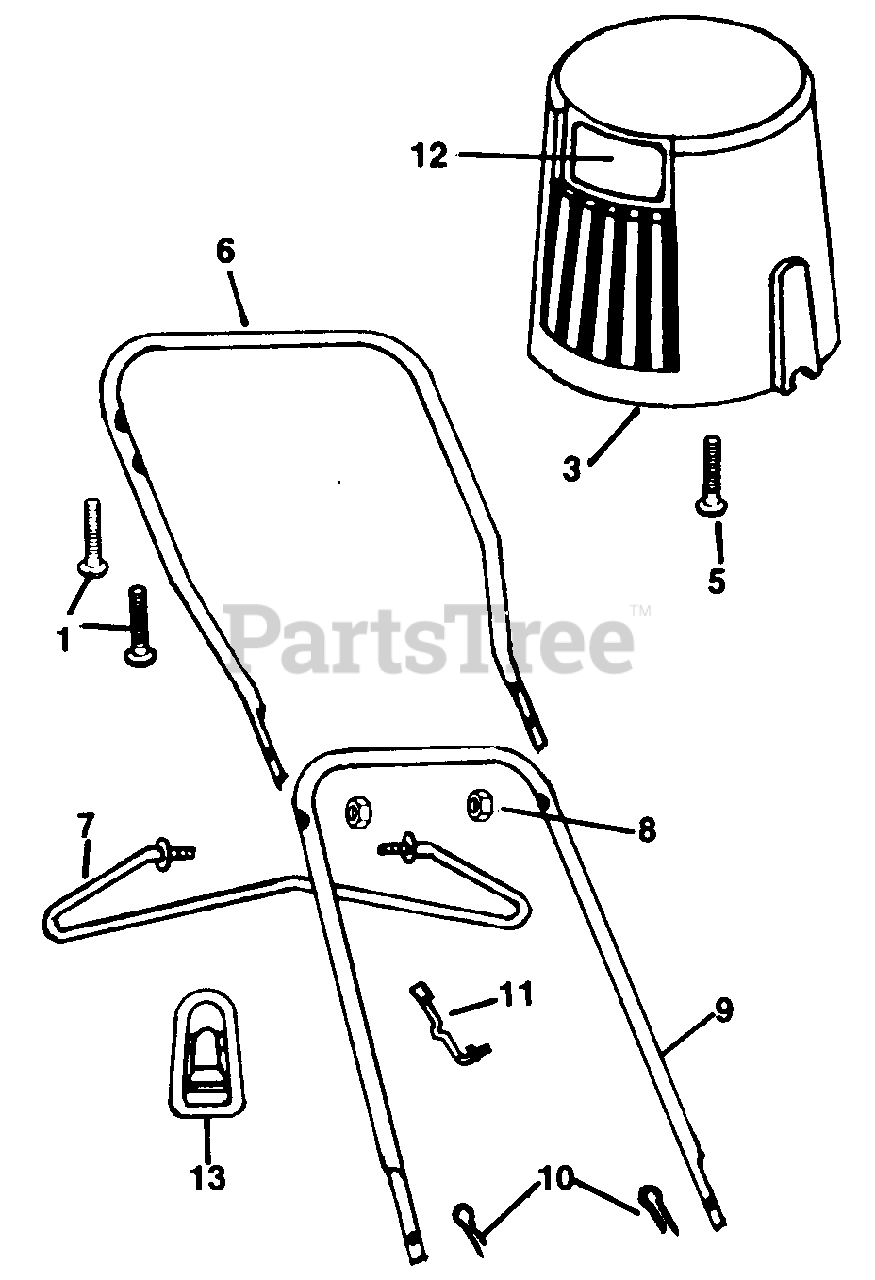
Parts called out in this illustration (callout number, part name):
1	Screw
3	Plastic Shroud
5	10-16 x 3/4" T25 Tapping
6	Upper Handle
7	Cord Control Rod
8	1/4"-20 Locknut
9	Lower Handle
10	CoKer Pin 3/32" x 1/2
11	Cord Tie
12	Warning Decal
13	Strain Relief
